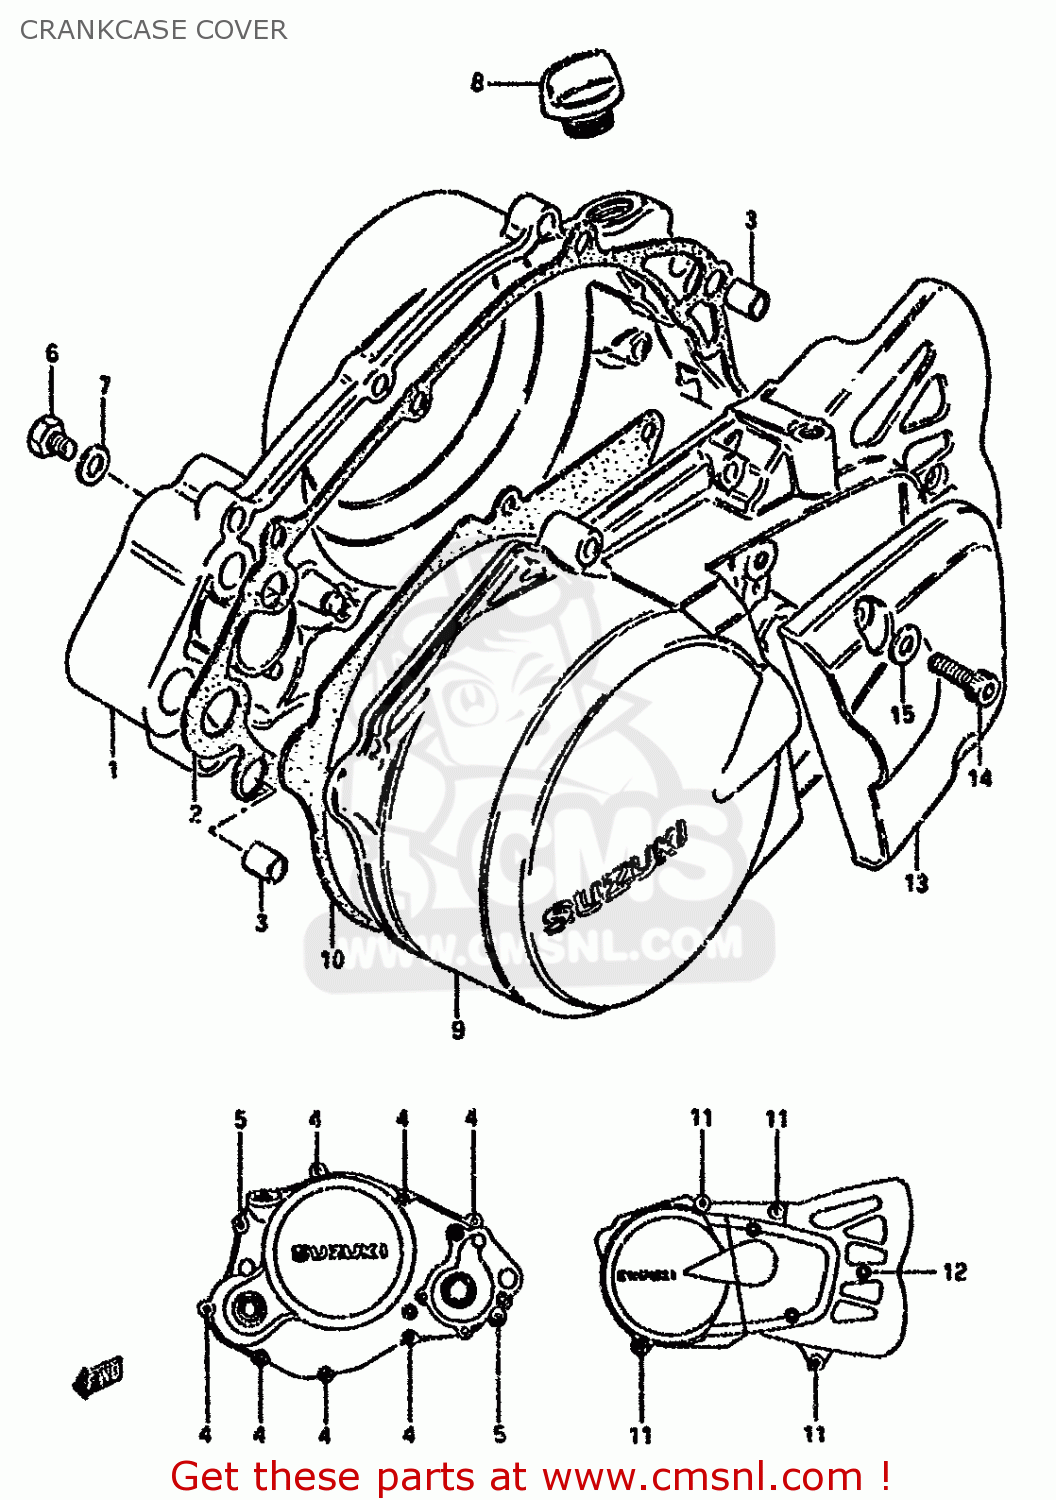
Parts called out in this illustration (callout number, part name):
1	COVER,CLUTCH
2	GASKET,CLUTCH COVER (NAS)
3	PIN
4	SCREW
5	SCREW
6	SCREW(6X10)
7	GASKET(6.2X11X1) (NAS)
8	PLUG SET
9	COVER,MAGNETO
10	GASKET,MAGNETO COVER (MCA)
11	SCREW(5X25)
12	SCREW
13	CAP,CLUTCH RELEASE ADJUST
14	SCREW
15	WASHER,5MM
